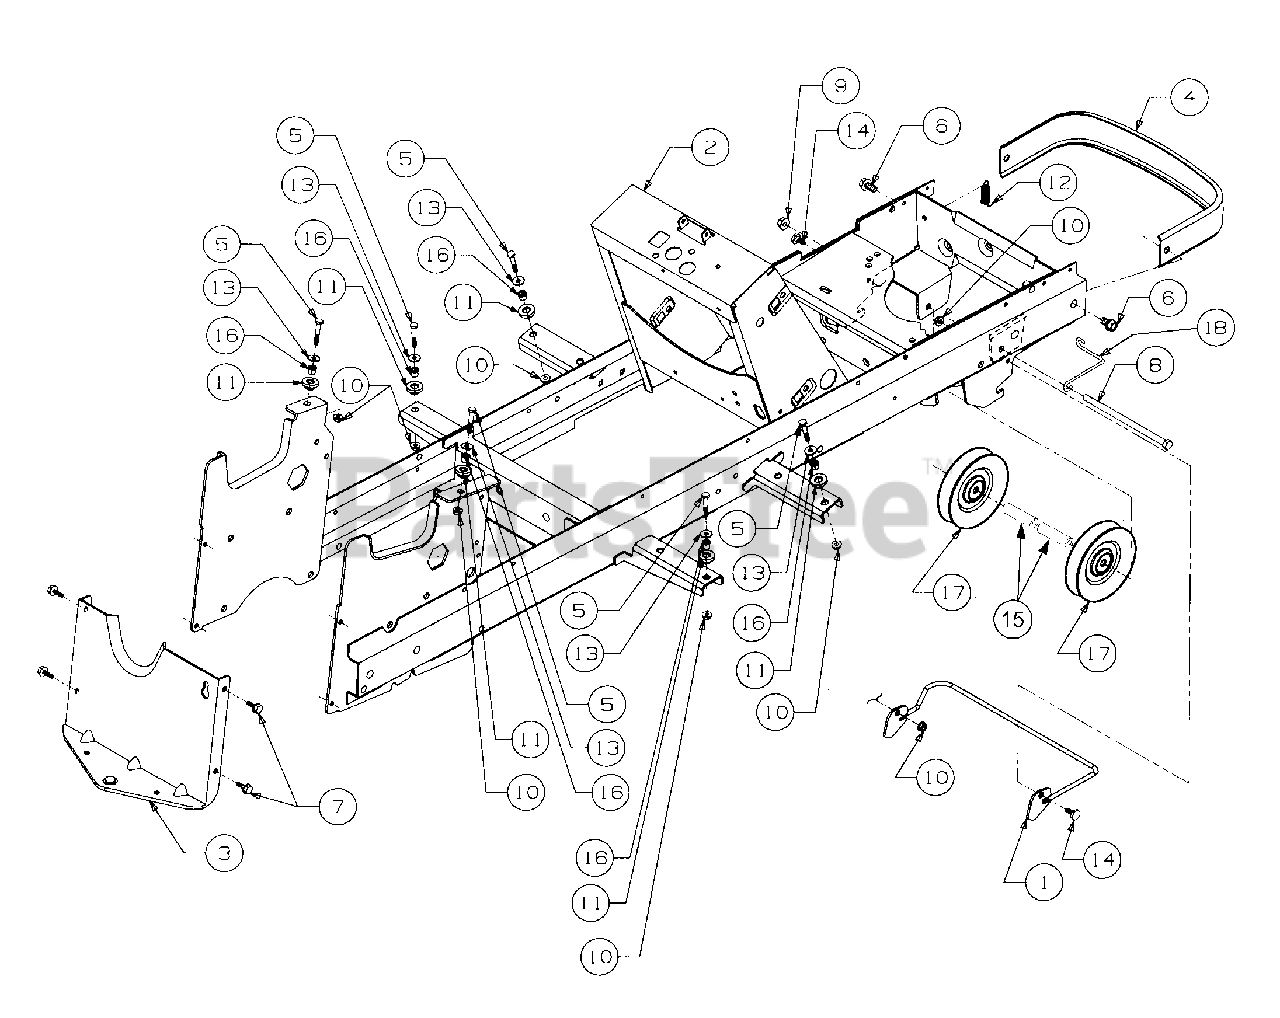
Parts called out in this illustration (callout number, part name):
6	Screw, Hex Wsh Hd Tapp 3/8-16 x .75
7	Screw, Hex Wsh Hd Tap 5/16-18 x .75
8	Screw, Hex Cap, 3/8-16 x 7.0
9	Nut, Hex Flange Lock, 3/8-16
10	Nut, Hex Flange Lock, 1/4-20
11	Grommet, Insulator
12	Spring, Latch
13	Washer, Flat, .255 x .72 x .60
14	Bolt, Shoulder
15	Spacer, Idler, .411 x .720 x 2.19
16	Spacer, .28 x .40 x .42 Lg
17	Pulley, Idler
18	Belt Guide
